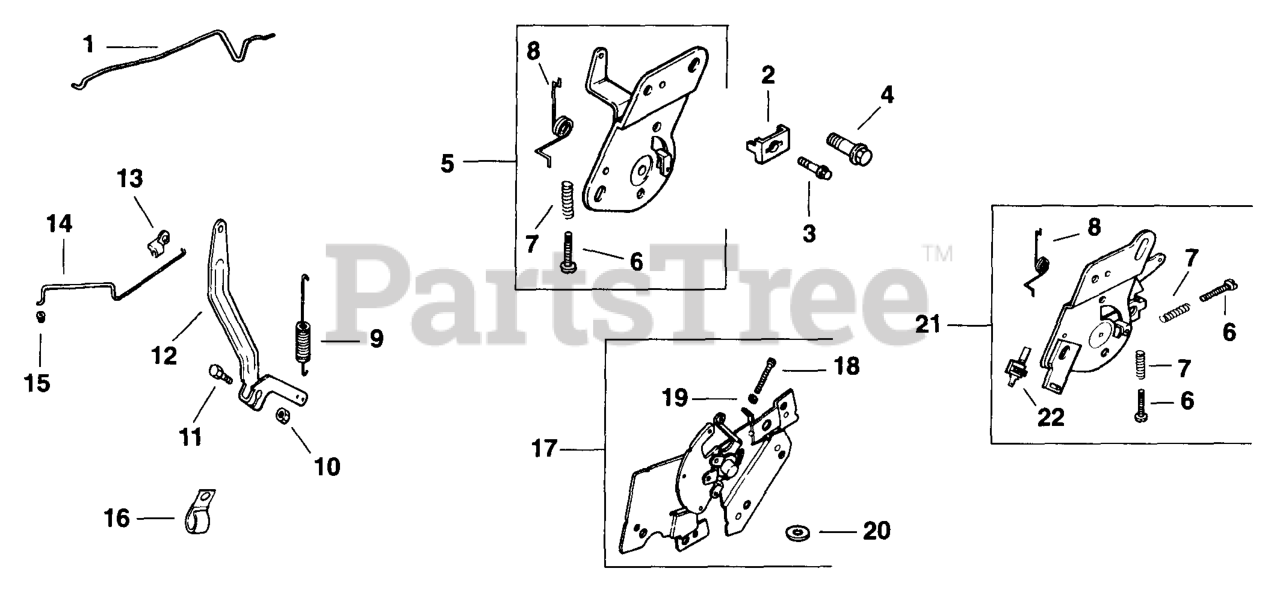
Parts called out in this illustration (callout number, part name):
1	Linkage, Choke
2	Clamp, Cable
3	Screw, Hex. Flange M5x0.8x16
4	Screw, Hex. Flange M6x1.0x16
6	Screw, Pan Hd. M4x0.7x25
7	Spring, Choke
8	Spring, Choke Return
9	Spring, Governor
10	Nut, Hex. Flange M6x1.0
11	Screw, Hex. Cap M6x1.0x25
12	Lever, Governor
13	Bushing, Linkage Black
14	Linkage, Throttle
15	Bushing, Linkage Natural
21	Speed Control Assembly
22	Terminal, Kill Switch
